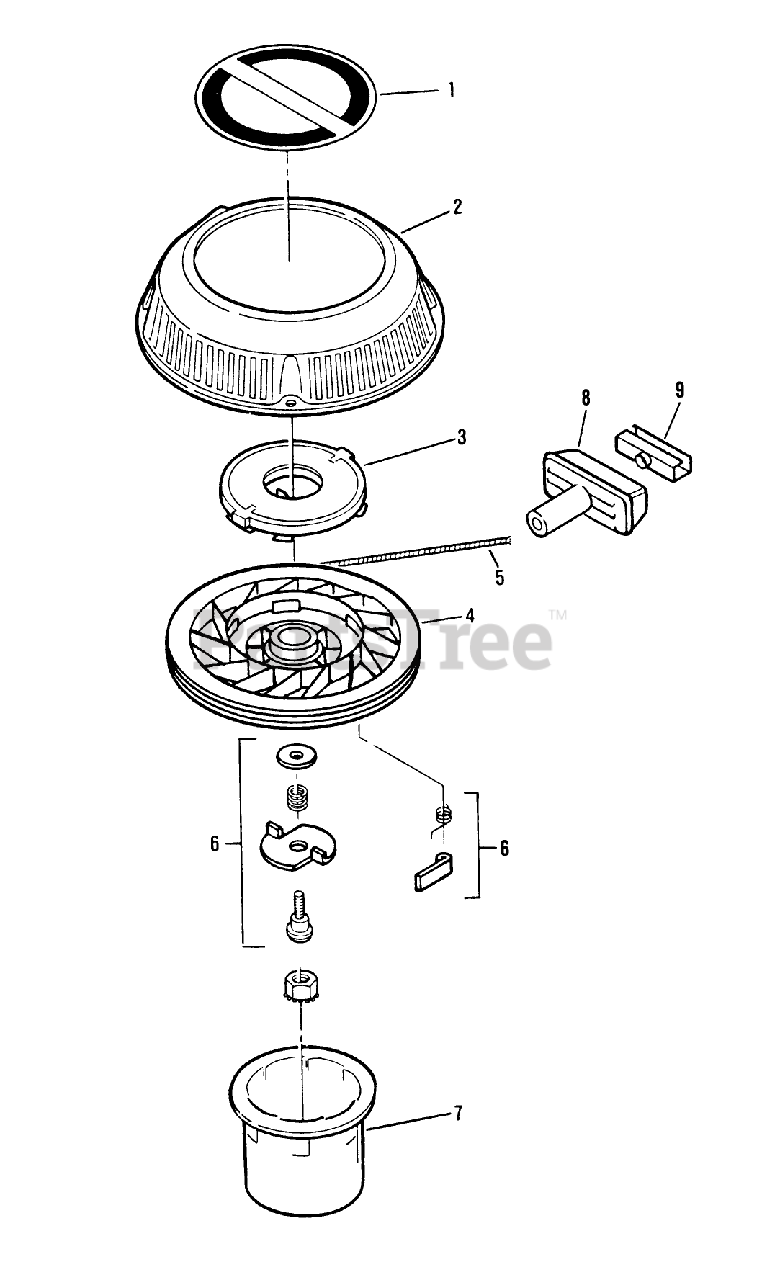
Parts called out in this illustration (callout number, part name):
4	PULLEY
6	DOG KIT
7	HUB-STARTER E COMM.
9	CLIP-STARTER
